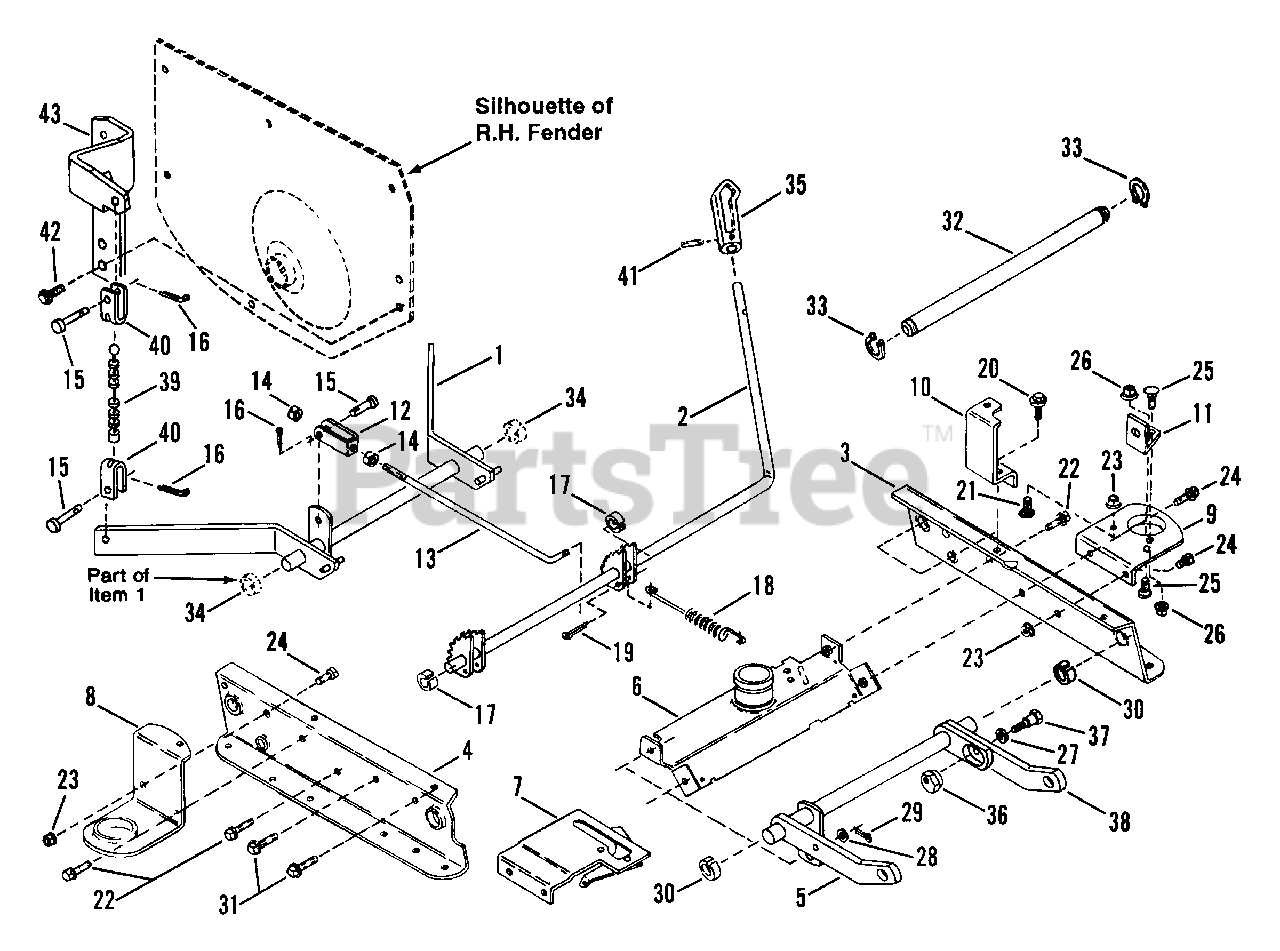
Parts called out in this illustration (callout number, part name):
1	ASSEMBLY, Rear Lift Arm
2	LIFT LEVER, Height Adjustment
3	RAIL, Left Half
4	RAIL, Right Half
5	STRUCTURE, Front Lift Arm
6	BRACE, Weldment
7	ASSEMBLY, Clutch P
8	SPINDLE, Brace, Right
9	SPINDLE, Brace, Left Half
10	BRACKET, Cover
11	ANCHOR
12	CLEVIS, Timing Rod
13	ROD, Timing
14	NUT, 3/8-24 Hex
15	PIN, 3/8 x 1 1/16" Clevis
16	PIN, 3/32 x 3/4" Cotter
17	RING, Black
18	SPRING, Cam-Lift
19	PIN, 5/32 x 1" Cotter
20	SCREW, 1/4-20 x 5/8" Self-Tapping
21	SCREW, 3/8-24 x 1" Hex Head Cap
22	SCREW, 3/8-16 x 1" Hex Washer Self-Tapping
23	NUT, 3/8-24 Lock
24	SCREW, 3/8-24 x 3/4" Hex Head Cap
25	BOLT, 5/16-18 x 3/4" Carriage
26	NUT, 5/16-18 Hex Flange Lock
27	WASHER, 3/8 Internal Tooth Lock
28	WASHER, 3/8
29	PIN, 1/8 x 3/4" Cotter
30	RING, Red
31	SCREW, 5/16-18 x 5/8" Hex Head Washer, Self-Tapping
32	SUPPORT, Rod
33	RING, Retaining
34	RING, Blue
35	GRIP, Height Adjustment Lever
36	ECCENTRIC, Leveling
37	BOLT, Shoulder
38	ARM, Front Lift, Left Side
39	CABLE, 41" Deck
40	BRACKET, Cable
41	ROLL-PIN, 3/16 x 3/4"
42	SCREW, 5/16-18 x 1" H.W.H., Self-Tapping
43	DECK WING, Rear
